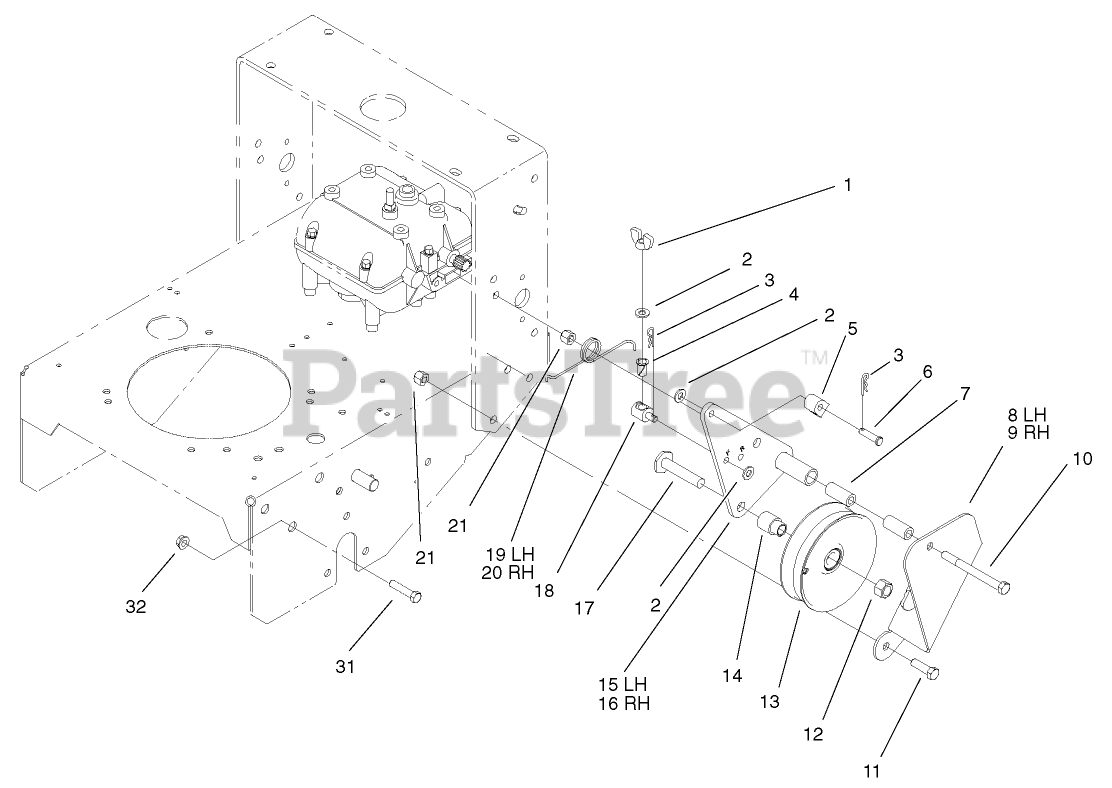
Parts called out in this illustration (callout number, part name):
1	NUT-WING
2	WASHER-PLAIN
3	PIN-COTTER
4	BUSHING-NYLON
5	FITTING-ROD
6	PIN-CLEVIS
7	SPACER-PIVOT, IDLER
8	BRACKET-SUPPORT, LH
9	BRACKET-SUPPORT, RH
10	SCREW-HH
11	SCREW-HH
12	NUT-LOCK, NI
13	PULLEY-IDLER
14	SPACER-PULLEY
15	BRACKET-IDLER, LH
16	BRACKET-IDLER, RH
17	SCREW-LEVELER
18	FITTING-ROD
19	SPRING-TORSION, LH
20	SPRING-TORSION, RH
21	NUT-LOCK, NI
31	SCREW-HHF
32	NUT-HF
